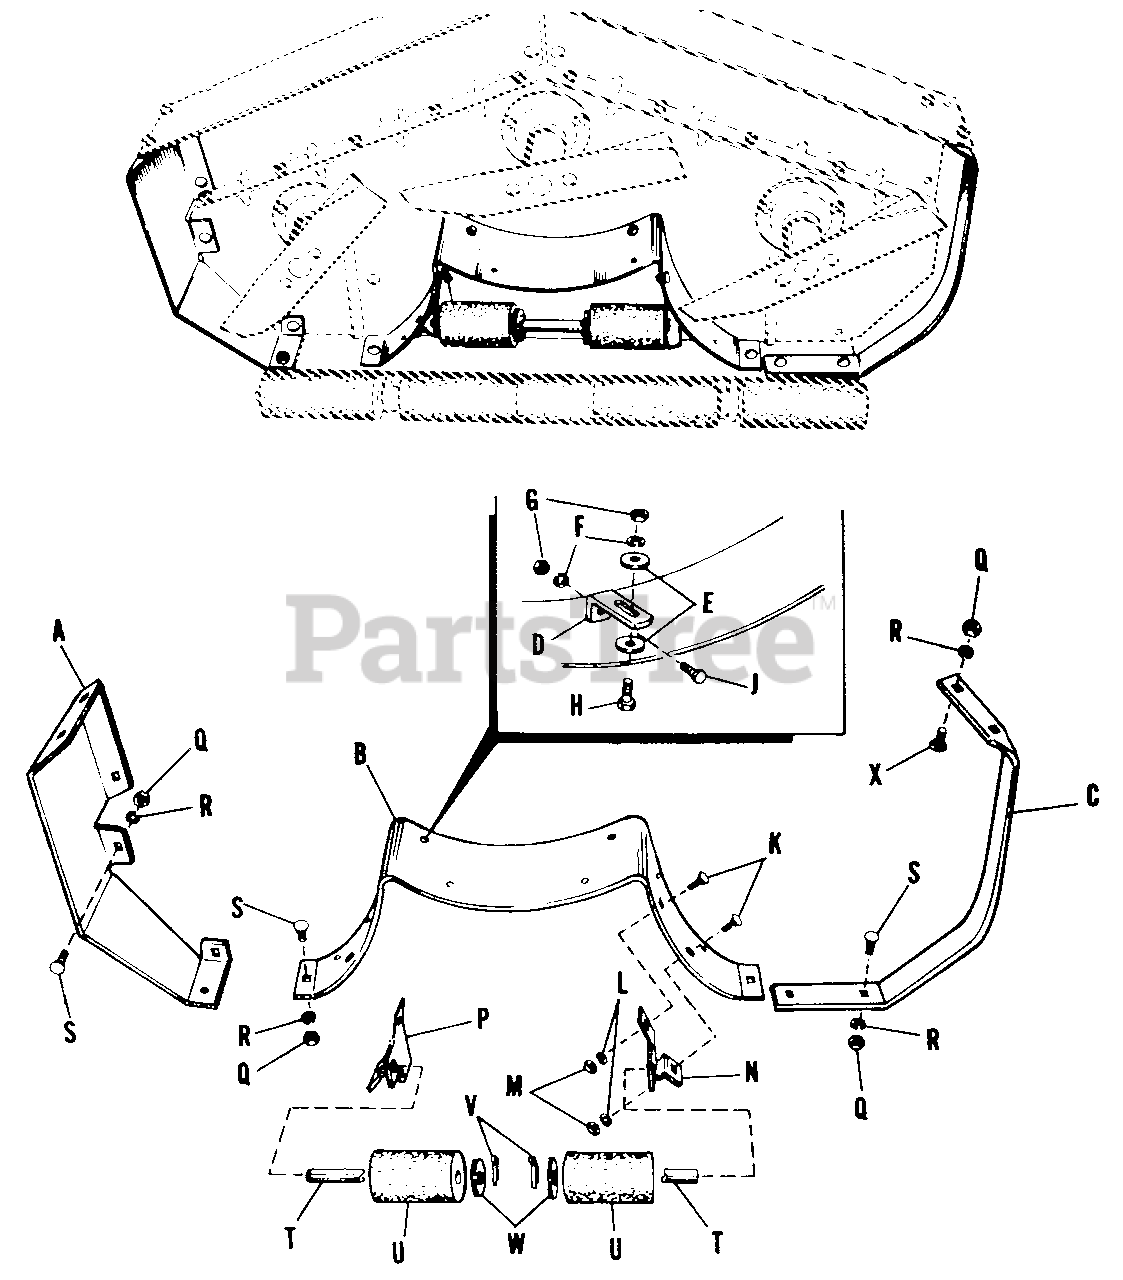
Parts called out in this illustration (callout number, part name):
A	Plate, End, Housing
C	Guard Assembly, Housing
D	Clip, Baffle
E	Washer, Plain, 1/4"
F	Washer, Lock, 1/4"
G	Nut, Hex, Full, 1/4"-20 NC
H	Capscrew, Hex, 1/4"-20 NC x 5/8"
J	Screw, Recessed Hex, Self Tapping 1/4"-20 NC x 7/8" lg.
K	Bolt, Carriage, 5/16"-18 NC x 3/4" lg.
L	Washer, Lock, 5/16"
M	Nut, Hex, Full, 5/16"-18 NC
N	Bracket, Roller, Lower, L.H.
P	Bracket, Roller, Lower, R.H.
Q	Nut, Hex, Full, 3/8"-16 NC
R	Washer, Lock, 3/8"
S	Bolt, Carriage, 3/8"-16 NC x 3/4" lg.
T	Shaft, Roller
V	Pin, Cotter, 3/16" x 1" lg.
X	Bolt, Carriage, 3/8"-16 NC x 1" lg.
